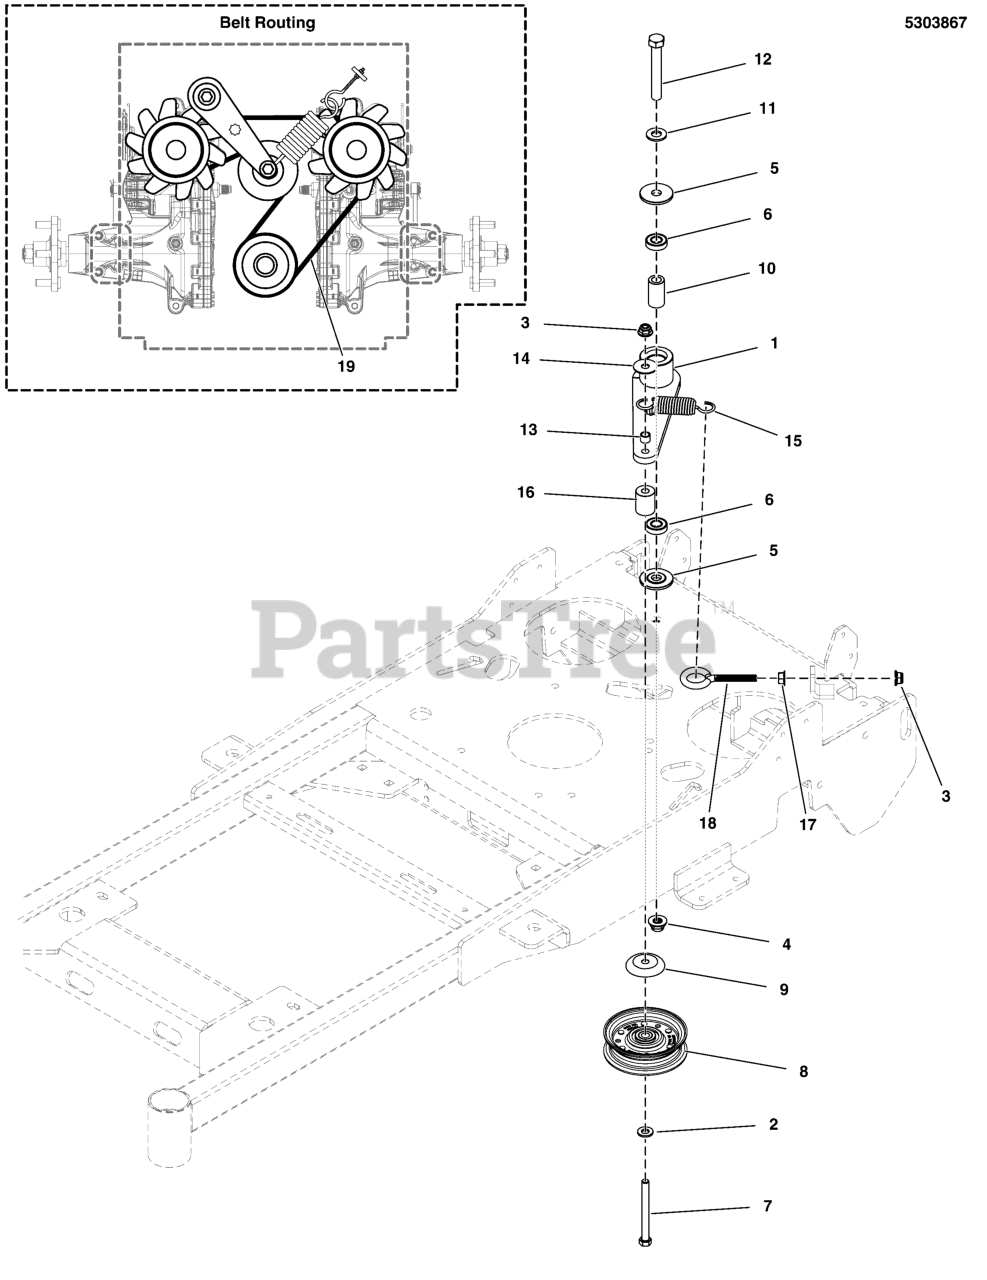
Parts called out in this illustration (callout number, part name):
1	WELD, IDLER ARM, 6.63" LG - BLK
2	WASHER, 3/8" GR. 9 FLAT
3	NUT, 3/8 - 16 HEX NYLOCK FLANGE
4	NUT, Hex Flange, Nylock, 1/2-13
5	SPACER, IDLER ARM, 1/2, PM
6	BEARING, BALL, AXLE
7	BOLT, 3/8-16 X 3-1/2" GD5 CZ
8	PULLEY, FLAT IDLER, FLG, 4"ODX3/8"ID, CZ
9	SHIELD, BEARING PULLEY, 3/8ID, CZ
10	SPACER, .52 X .84 X 1.53, PM
11	WASHER, 1/2 SAE
12	BOLT, 1/2-13 X 3-1/2, HEX HD, GD5, CZ (SV)
13	SPACER-0.385ID 0.623OD 0.290LG P'MTL
14	WASHER, 3/8" USS
15	SPRING-EXT, 1.125 ODX4.679LGX.146WR, BLK
16	SPACER, .39 X 1.00 X 1.25, PM, CZ
17	NUT, 3/8-16 Hex Large Serrated Flange
18	EYEBOLT, 3/8-16 X 4, 2.13THRD, .75EYE, C
19	BELT, A-SEC, COG TYPE, 57" EL, ARAMID
